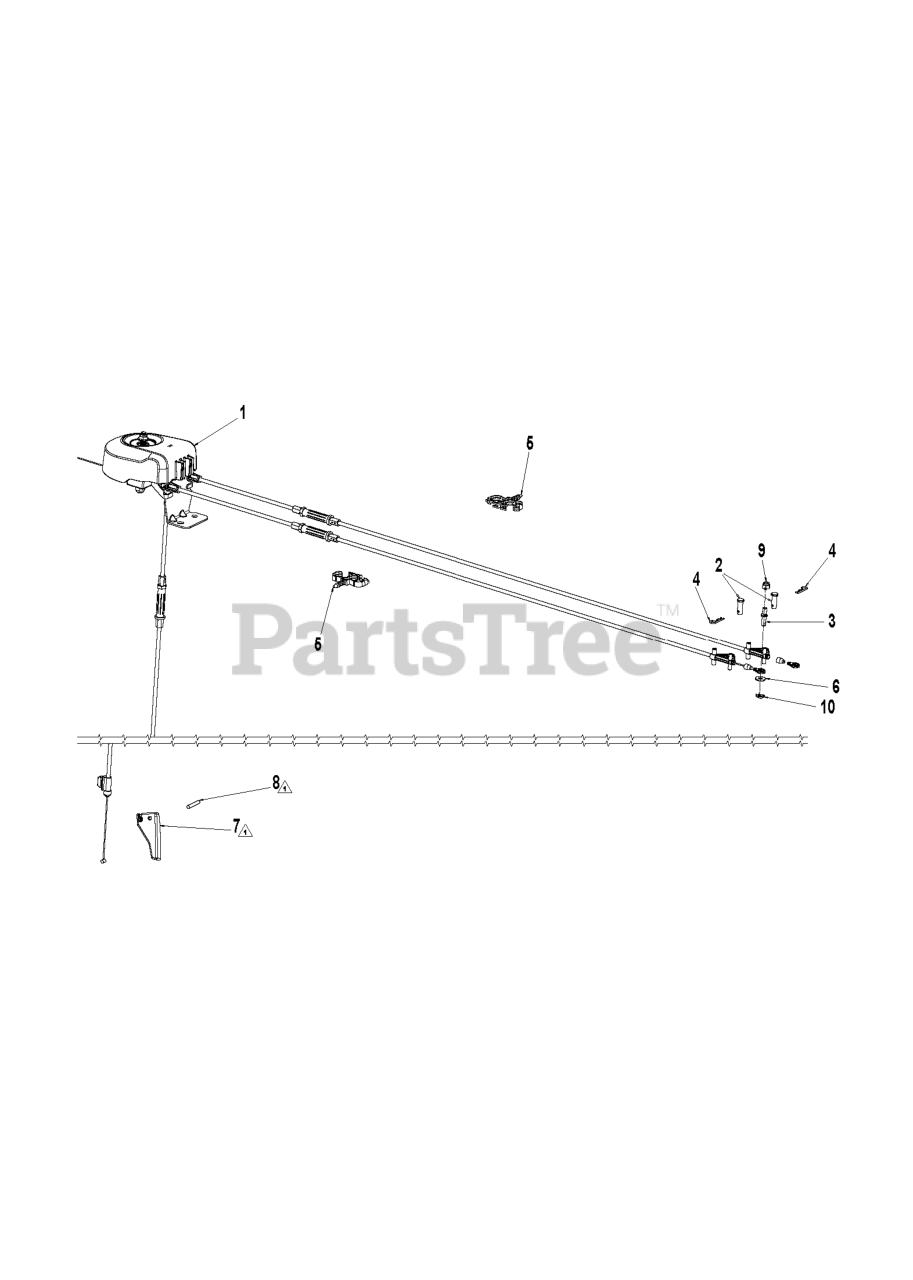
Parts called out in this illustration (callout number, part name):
1	CABLE CHUTE ROTATOR ASM LOCKIN
2	PIN CLEVIS 5/16X.875
4	HAIRPIN.SOFT.ZINC.059X1.125
5	CLIP.CONDUIT.DOUBLE LOOP
6	WASHER FLAT_.250 X .625 X .06
8	PIN, ROLL 3/16 X 1-1/8
9	NUT HEXAGON 1/4-20 ST ZPB
10	GSPW Retainers
